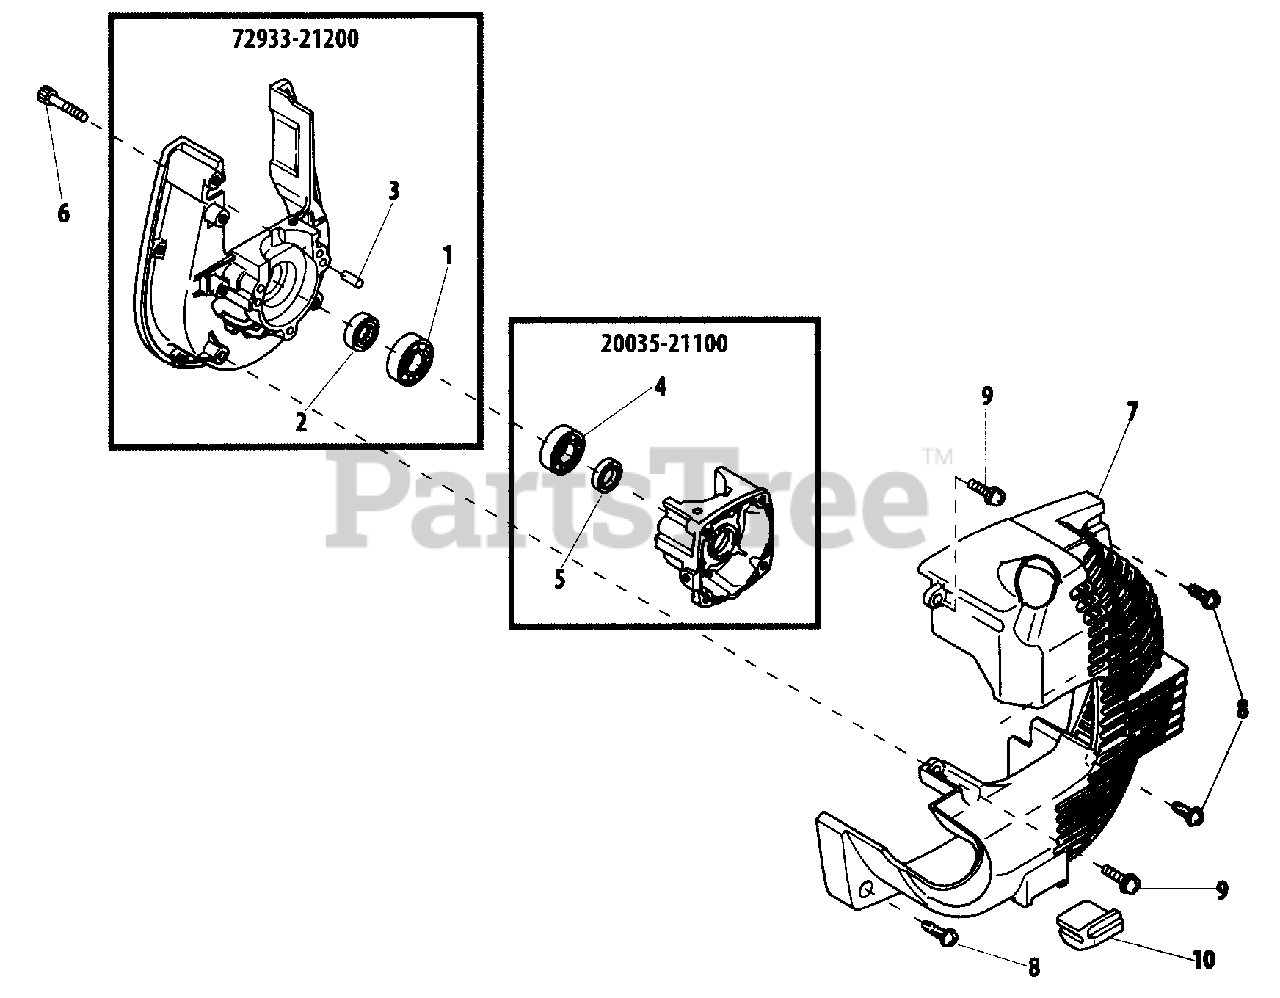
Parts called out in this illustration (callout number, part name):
1	BEARING, BALL
2	SEAL, OIL 12
3	PIN, LOCATING Ø4×8
4	BEARING, BALL 6001 C3
5	SEAL, OIL 12
6	BOLT 5×25
7	COVER, ENGINE
8	SCREW 5×20
9	SCREW
10	CUSHION
